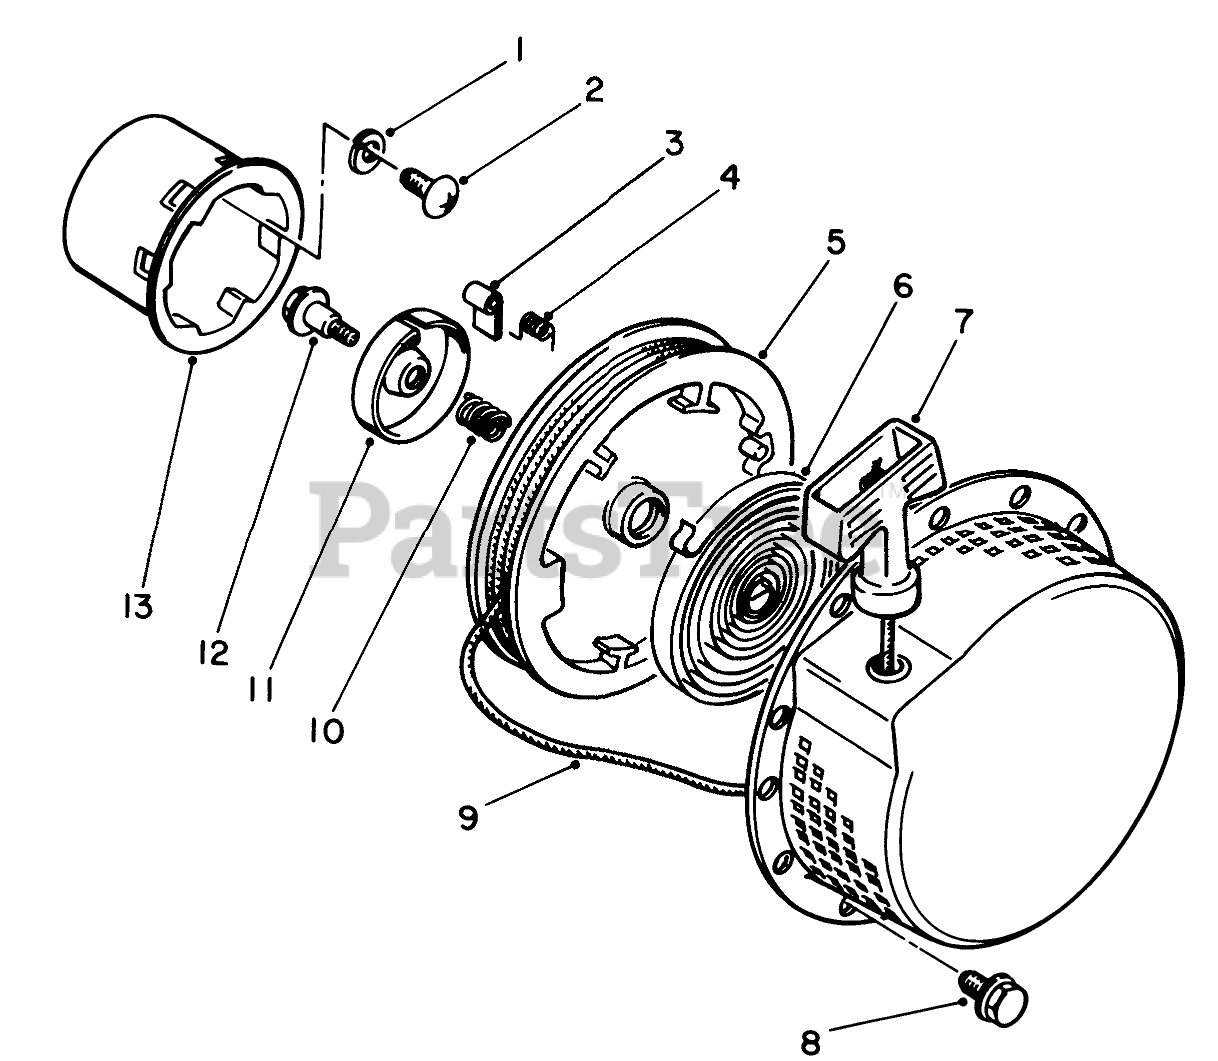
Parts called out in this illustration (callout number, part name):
1	Washer-Lock
2	Screw
4	SPRING
6	SPRING
7	Grip-Hand
9	Starter Rope Assembly (Incl.Ref. #7)
10	SPRING
11	RETAINER
13	Pulley
